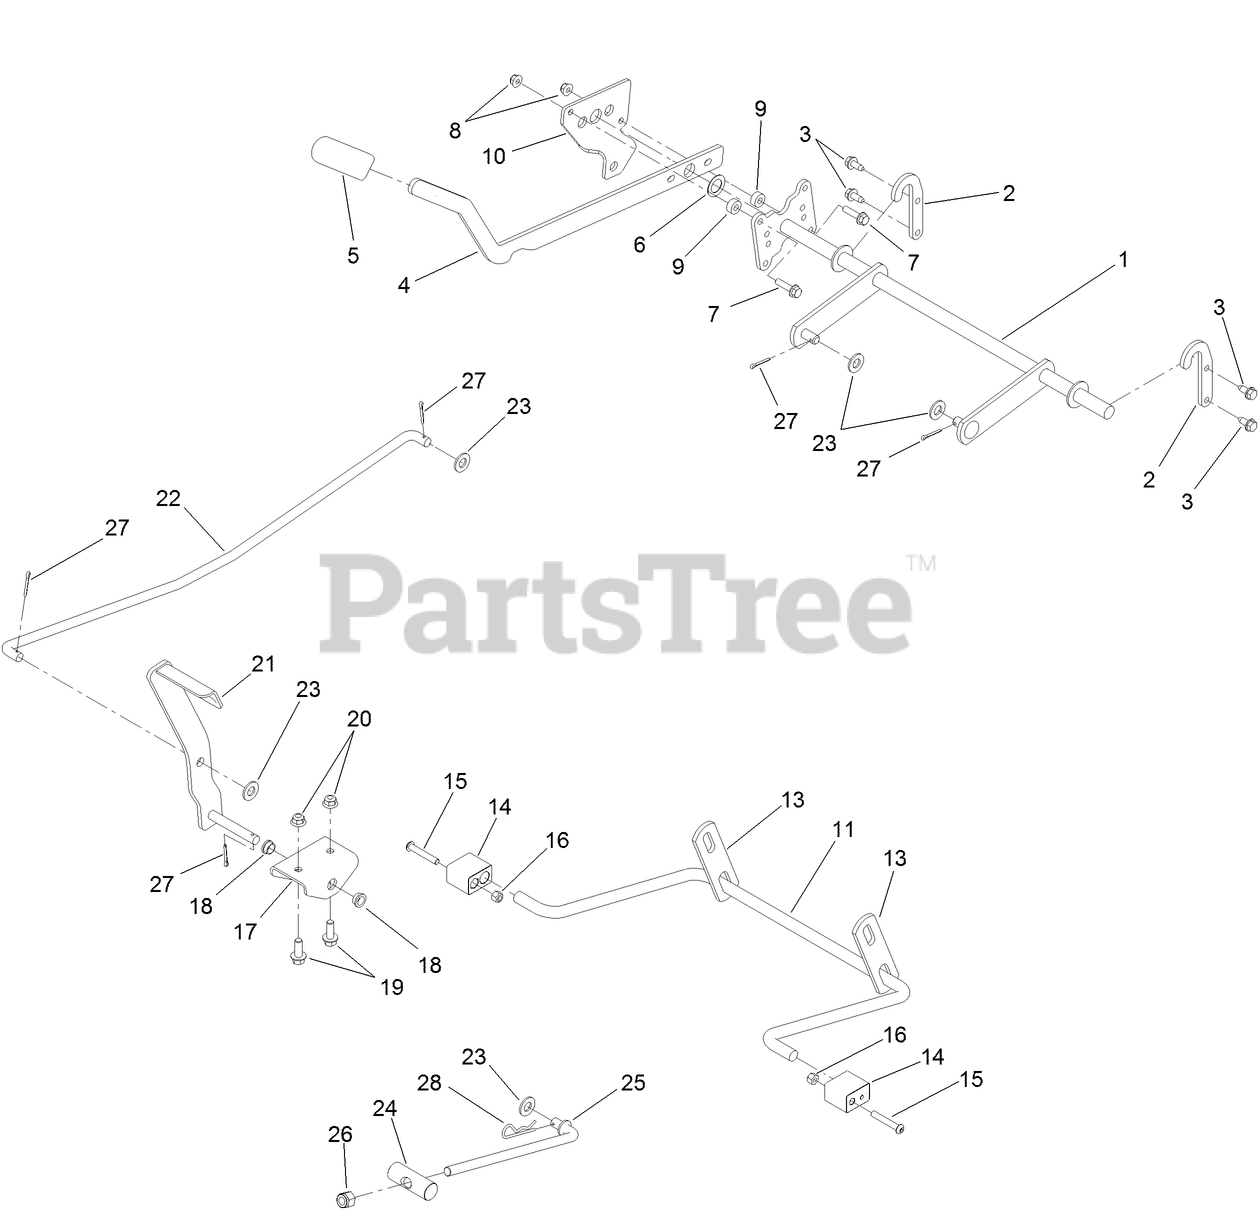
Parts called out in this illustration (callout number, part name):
1	LIFT-DECK, NARROW
2	BRACKET-LIFT
3	SCREW-HWHTF
4	LEVER-LIFT
5	GRIP-LEVER
6	WASHER-THRUST
7	SCREW-HHF
8	NUT-HF, NI
9	SPACER
10	PLATE-FOOTLIFT
11	ARM-LIFT, REAR
13	LINK-LIFT
14	BLOCK-PIVOT
15	SCREW-HSBH
16	NUT-LOCK, NI
17	BRACKET-FOOTLIFT
18	BUSHING-FLANGE
19	SCREW-HHF
20	NUT-HF, NI
21	PEDAL ASM
22	ROD-FOOTLIFT
23	WASHER-FLAT
24	PIN-PIVOT
25	ROD-MOUNT, DECK
26	NUT-HEX
27	PIN-COTTER
28	PIN-COTTER
